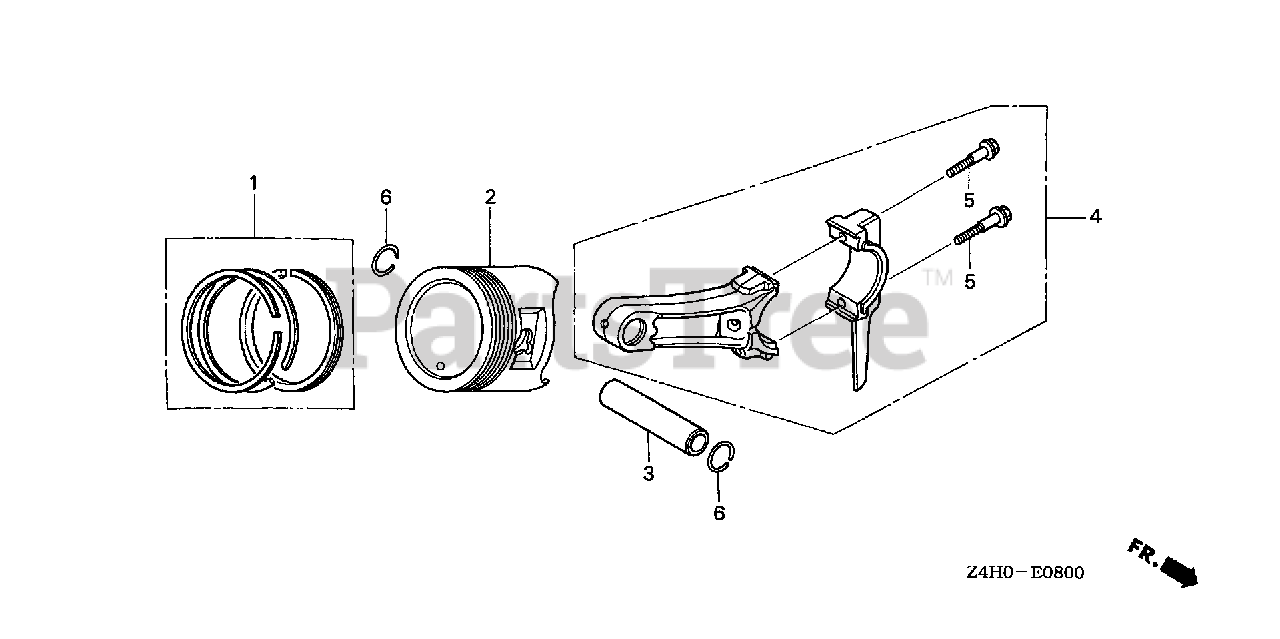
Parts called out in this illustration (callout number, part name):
1	RING SET, PISTON (STD) (TEIKOKU)
1	RING SET, PISTON (STD) (RIKEN)
1	RING SET, PISTON (0.25) (TEIKOKU)
1	RING SET, PISTON (0.25) (RIKEN)
1	RING SET, PISTON (0.50) (TEIKOKU)
1	RING SET, PISTON (0.50) (RIKEN)
1	RING SET, PISTON (0.75) (TEIKOKU)
1	RING SET, PISTON (0.75) (RIKEN)
2	PISTON (STD)
2	PISTON (0.25)
2	PISTON (0.50)
2	PISTON (0.75)
3	PIN, PISTON
4	ROD ASSY., CONNECTING (UNDER SIZE)
4	ROD ASSY., CONNECTING
5	BOLT, CONNECTING ROD
6	CLIP, PISTON PIN (13MM)
